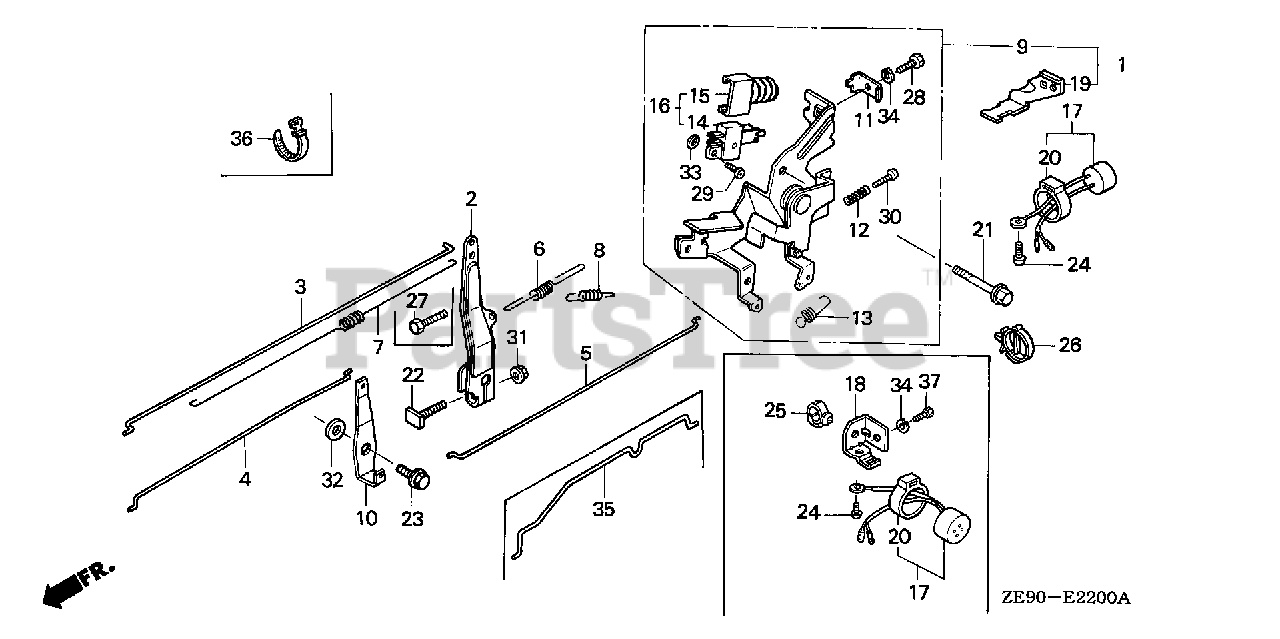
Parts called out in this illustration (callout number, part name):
2	ARM, GOVERNOR (NOT AVAILABLE)
3	ROD, GOVERNOR
4	ROD, CHOKE
5	ROD, JOINT
6	SPRING, GOVERNOR (NOT AVAILABLE)
8	SPRING, GOVERNOR PRIMARY
9	CONTROL ASSY.
9	CONTROL ASSY. (NOT AVAILABLE)
10	LEVER, CHOKE JOINT (NOT AVAILABLE)
11	HOLDER, CABLE
12	SPRING, CONTROL ADJUSTING
13	SPRING, CABLE RETURN
14	SWITCH ASSY., ENGINE
15	COVER, SWITCH
16	SWITCH ASSY., ENGINE STOP
17	BUZZER ASSY.
18	STAY, BUZZER
19	STAY, BUZZER
20	SUSPENSION, AUDIBLE PILOT
21	BOLT, FLANGE (6X12) (CT200)
22	BOLT, GOVERNOR ARM
23	BOLT, FLANGE (6MM)
24	SCREW, TAPPING (5X8)
25	CLIP, WIRE HARNESS (25MM)
26	CLIP, HARNESS
27	BOLT, HEX. (6X22)
28	BOLT, RECESSED (5X16)
29	SCREW, PAN (4X14)
30	SCREW, PAN (5X20)
31	NUT, FLANGE (6MM)
33	WASHER, SPRING (4MM)
34	WASHER, SPRING (5MM)
35	ROD, JOINT
36	BAND B1, WIRE
37	BOLT, RECESSED (5X16)
